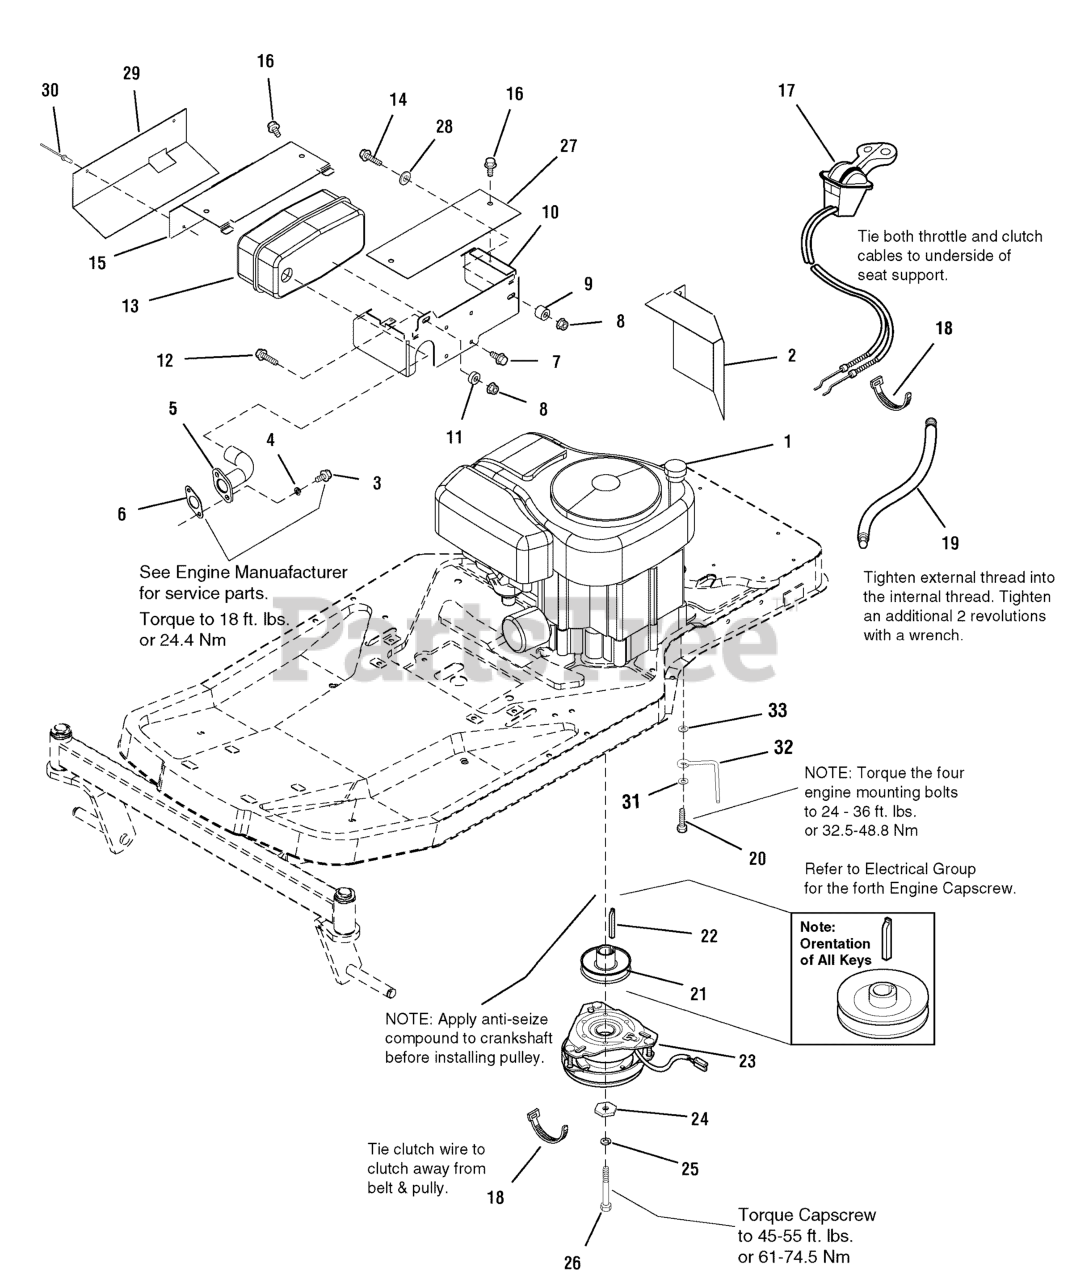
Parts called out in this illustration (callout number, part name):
2	SHIELD, Heat Inner
3	CAPSCREW, Hex Socket Head, 5/16-18 x 3/4
4	WASHER, Lock Helical Spring
5	PIPE ASSEMBLY, Exhaust
6	GASKET, Exhaust
7	CAPSCREW, Hex Flange, Whiz Lock, 1/4-20 x 5/8
8	NUT, Hex Flange Lock, Large, 5/16-18
9	SPACER, .390 ID .90 OD 0.70 Lg
10	BRACKET, Muffler Heat Resistent
12	CAPSCREW, Hex Head, 5/16-18 x 1 1/4
13	MUFFLER ASSEMBLY, Single
14	CAPSCREW, Hex Head, 5/16-18 x 1-1/2, G5
15	HEAT SHIELD, Single Cylinder
16	CAPSCREW, Thread Cutting, # 10 x 1/2
17	CONTROL, Throttle Double 42" Long
18	TIE, Self Locking, 3-5/8 LG
19	HOSE, Oil Drain
20	CAPSCREW, Hex Head, Taptite, 3/8-16 x 1-1/2 (For 1692768)
21	PULLEY, 3.74 OD x 1.003 ID x 1.88 LG
22	KEY, Hi-Pro, 1/4 x 2-1/2
23	CLUTCH, Electric Ogura
24	WASHER, Hex
25	LOCKWASHER, Spring, 7/16
26	CAPSCREW, Hex Head Cap, 7/16-20 x 2-3/4, GR5, Black
27	HEAT SHIELD
28	WASHER, 5/16
29	HEAT SHIELD
30	RIVET, Pop
31	WASHER, 3/8, .41 ID x .87 OD x .08 THK
32	RETAINER, Clutch
33	WASHER, Flat
